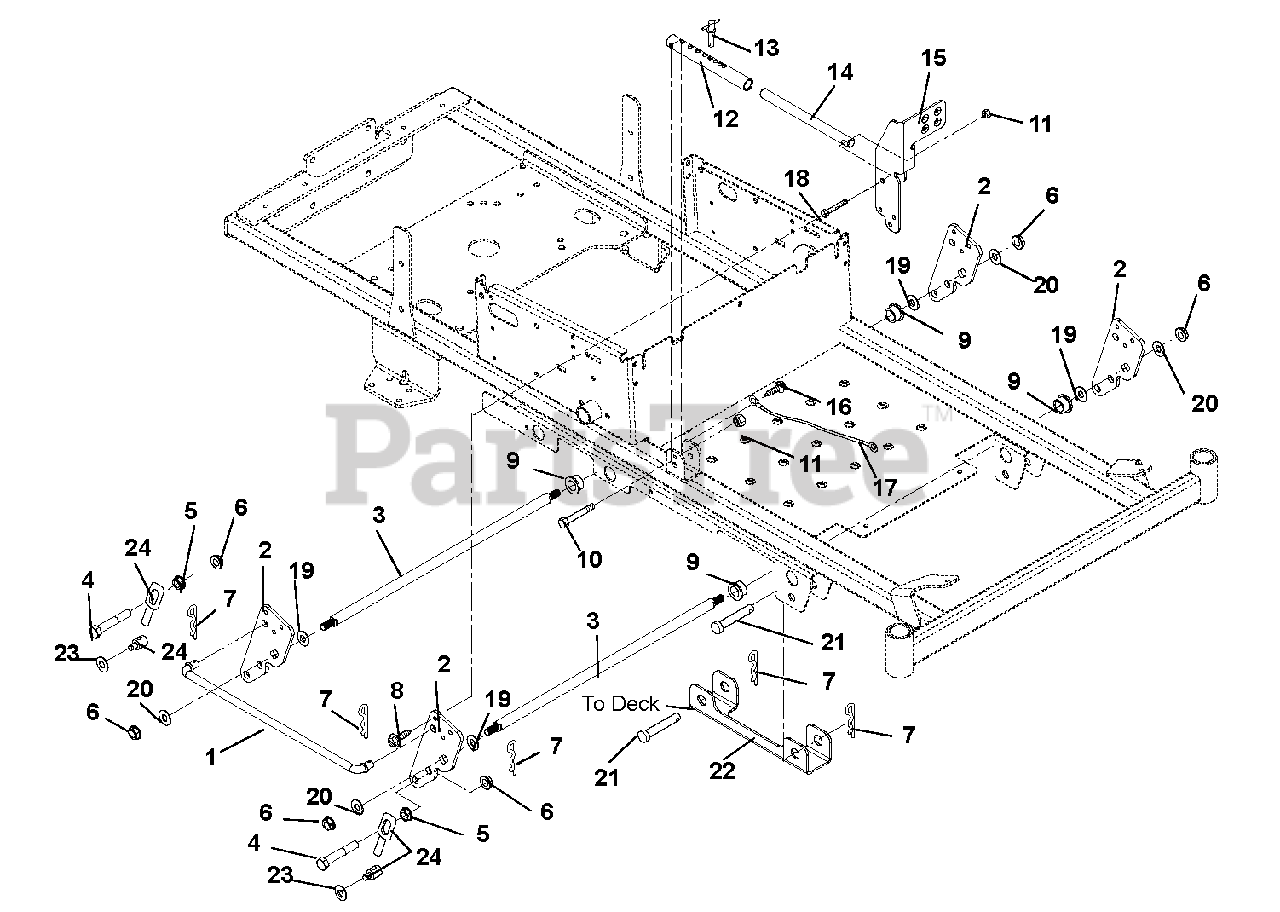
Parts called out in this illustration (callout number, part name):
1	Rod, Lift
2	Lift Arm
3	Shaft, Lift
4	Bolt, Hex .50-13 x 2.75 Grade 8
5	Nut, Spin Lock Flange .50-13
6	Nut .50-13 Nyloc Flange
7	Pin, Hair #16
8	Screw, Tap .31-18 x .50
9	Bushing, Flange .750 x 1.000 x .625 x 1.250
10	Bolt, Hex .38-16 x 2.00 Grade 5
11	Nut, Flange Nyloc 3/8-16
12	Tube, Lift Stop
13	Pin, Spring Ball .375OD x 1.50
14	Rod, Lift
15	Pedal, Foot Lift
16	Screw, Tap .25-20 x .50
17	Cable, 12.0 LANYARD, Nylon
18	Bolt, Hex .38-16 x 2.50 Grade 5
19	Washer, Flat Steel .755 x 1.375 x .062
20	Washer, Flat Steel .515 x 1.625 x .250
21	Pin, Clevis .494 x 2.50
22	Channel, Deck Lift
23	Washer, Flat Steel .511 x 1.441 x .125
24	Assembly, Deck Link
